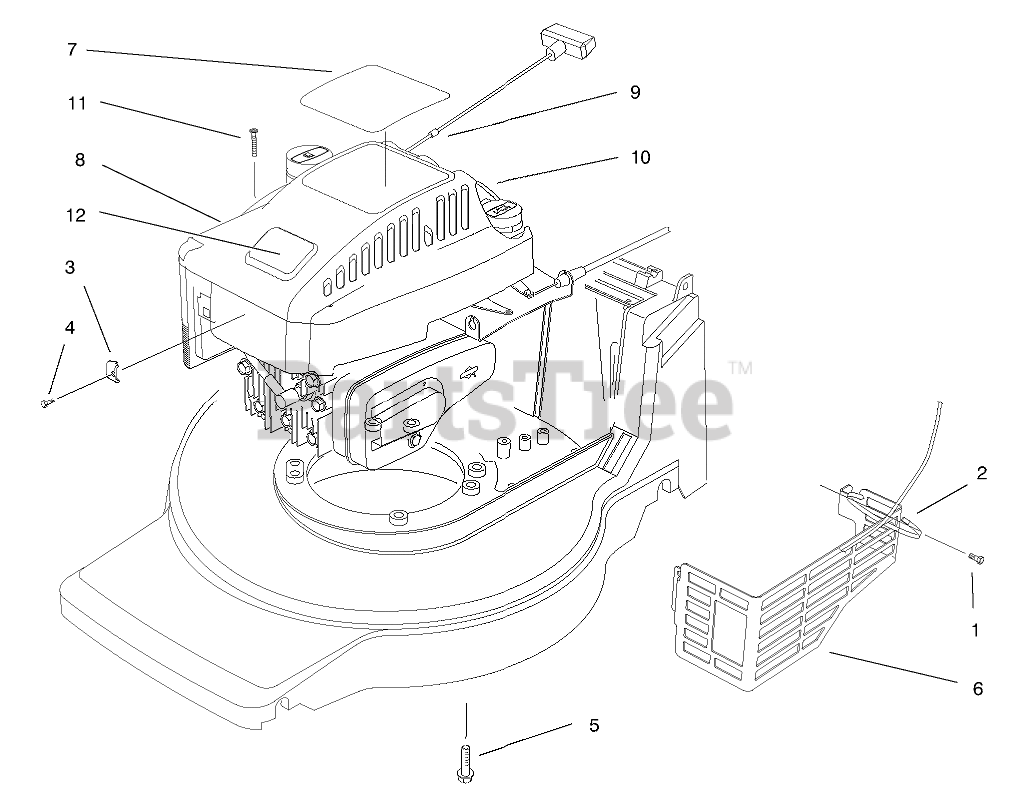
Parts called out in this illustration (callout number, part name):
1	SCREW-HWH
2	TIE-CABLE
3	CLAMP-CASING
4	SCREW-CLAMP
5	SCREW-HWH
6	SHIELD-MUFFLER
7	DECAL - RECOIL
9	STOP-ROPE
10	SHROUD-ENGINE
11	SCREW-PPH
12	PLATE-LOGO
